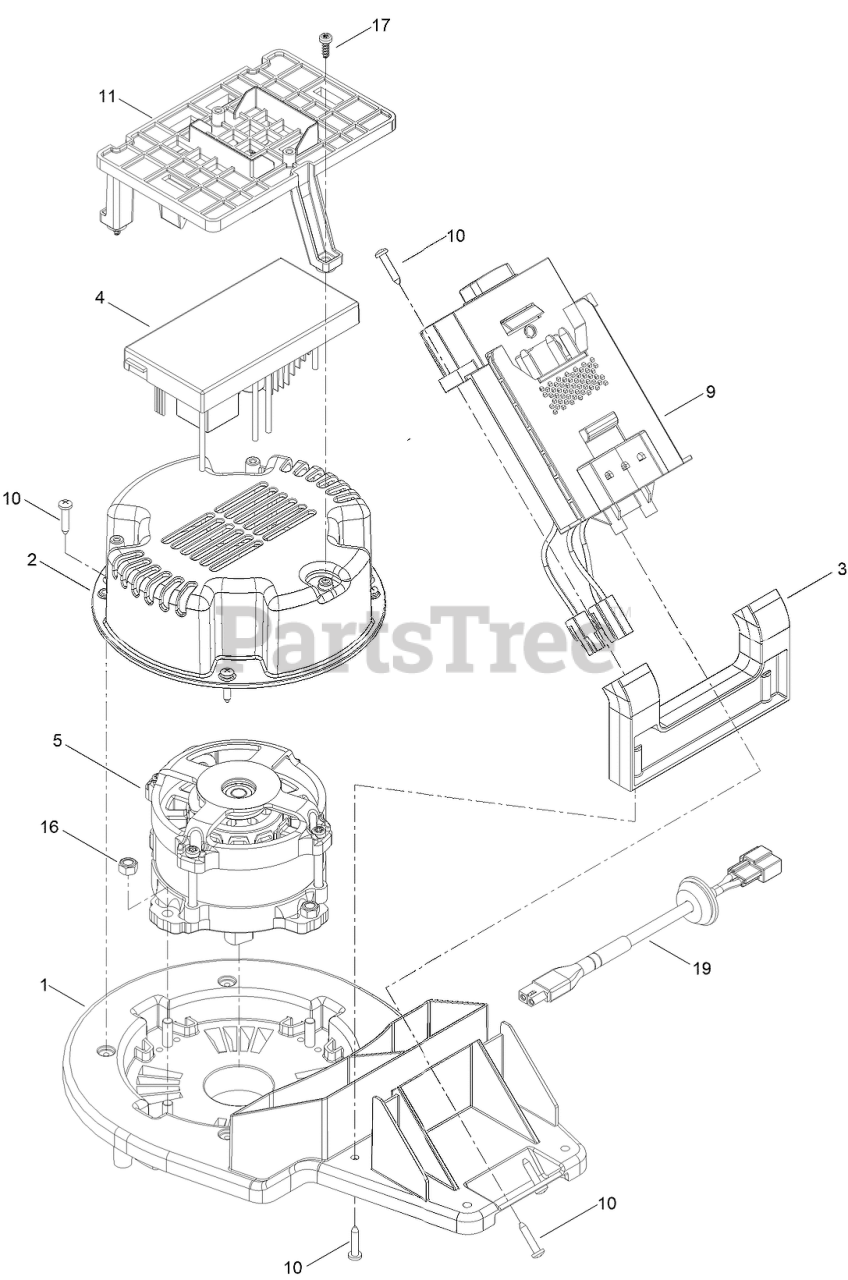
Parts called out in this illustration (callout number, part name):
1	ASM-MOUNT, MOTOR
2	COVER-MOTOR
3	SUPPORT-RECEIVER
4	CONTROLLER-MOTOR, SP NO LED
5	MOTOR-1KW, 60V
9	BATTERY TRACK ASM
10	SCREW-PPH, ST4.2x20
11	BRKT-CONTROLLER
16	NUT-HEX, M6
17	SCREW-TPH, ST4.2x12
19	ASM-WIRE, COBRA SP
